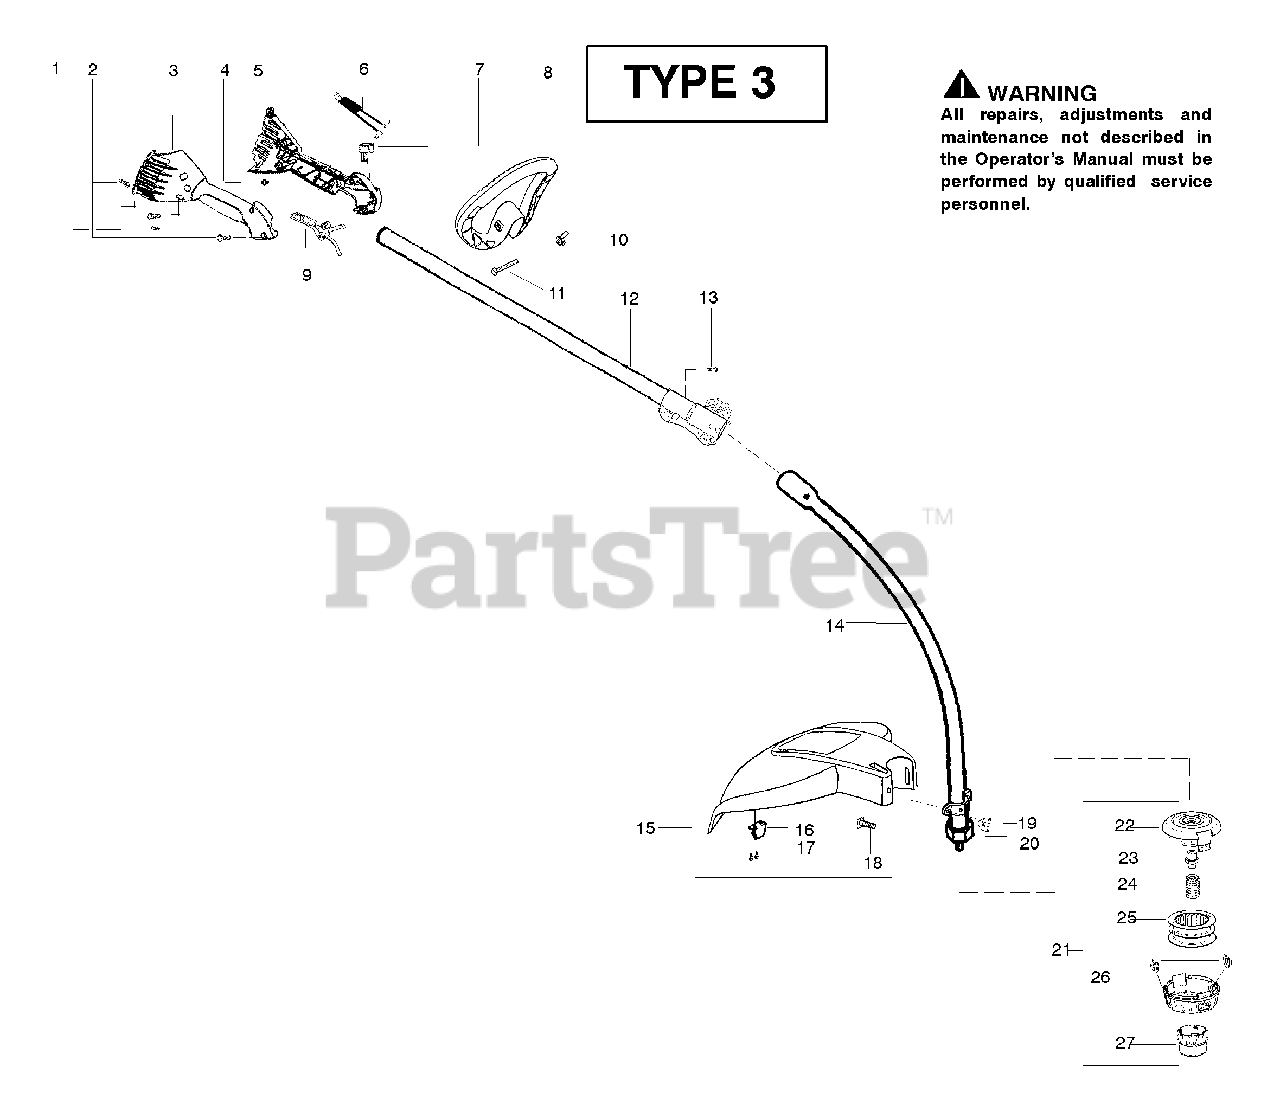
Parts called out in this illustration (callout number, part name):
1	Screw-alignment
3	Hsg.-Throttle right
4	Screw-Cable Retention
5	Hsg.-Left throttle
6	Assy-Wire
7	Kit-Switch
8	Assy-Assist Handle
9	Trigger-Throttle
10	Wingnut
12	Kit-Upper Shaft
14	Kit-Lower Shaft
15	Kit-Shield Assy.
16	Limiter-Line
19	Wingnut
21	Accy-TNG7 Head
25	Accy-Wound Spool
26	Kit-Cover and Eyelet
